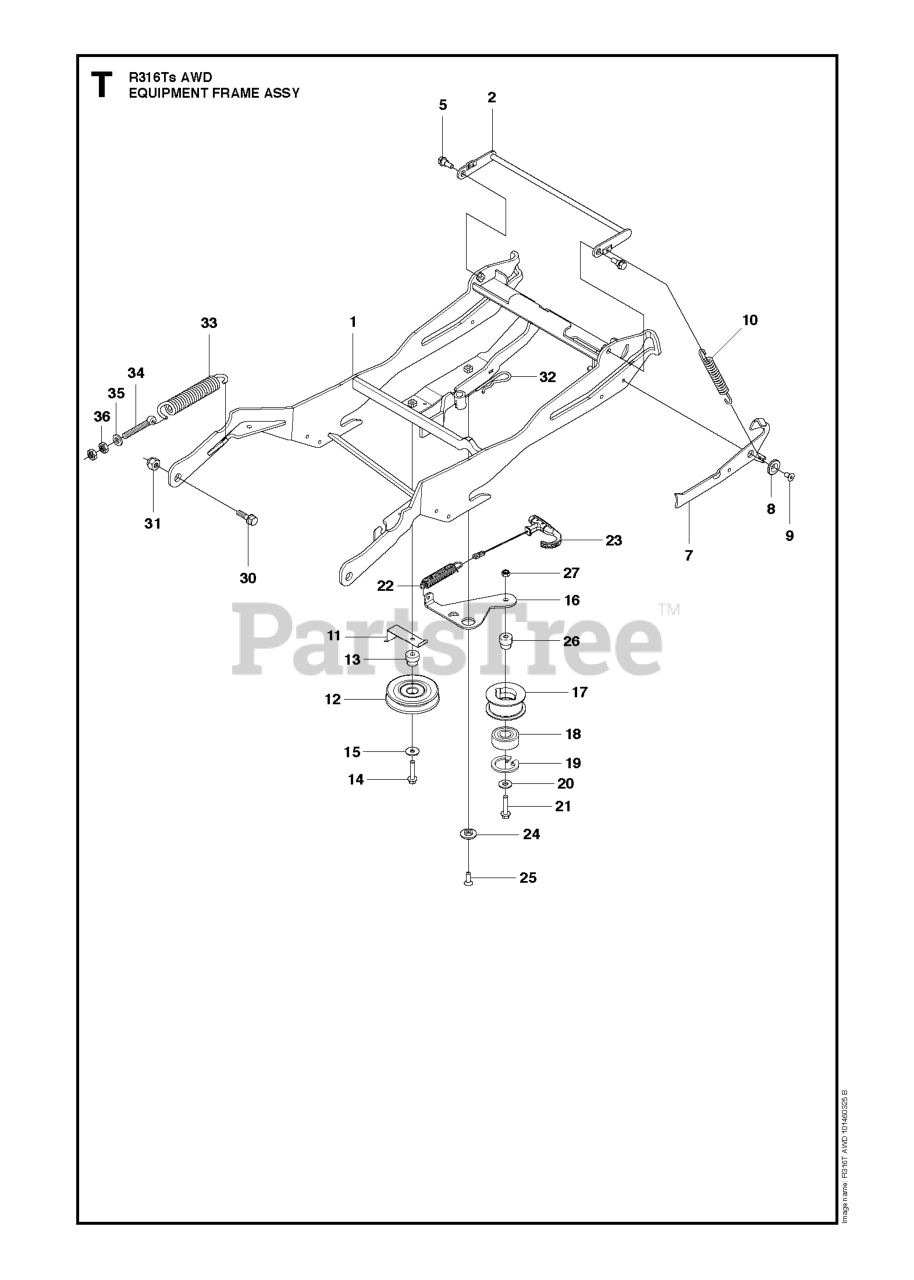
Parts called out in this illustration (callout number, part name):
1	SOCKET
2	HANDLEBAR ASSY
8	SCREW MC6S 5X10
14	FLAT NOZZLE
